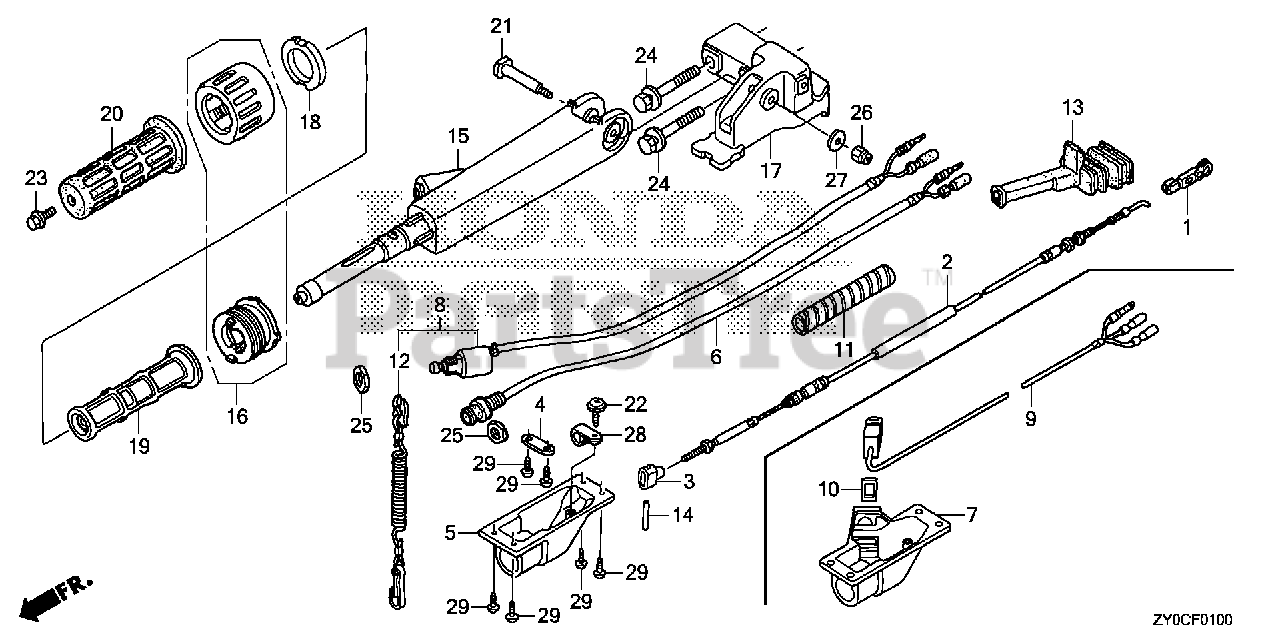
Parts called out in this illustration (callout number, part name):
1	LINKAGE, PIVOT
2	CABLE, THROTTLE
3	PIVOT, THROTTLE CABLE
4	PLATE, SHIFT
6	SWITCH ASSY., STARTER
7	COVER, SWITCH (PT)
8	SWITCH ASSY., EMERGENCY STOP
9	SWITCH ASSY., POWER TILT
10	STAY, POWER TILT SWITCH
11	TUBE, SPIRAL B
12	WIRE, EMERGENCY
13	GROMMET, OIL CASE (A)
14	PIN, THROTTLE CABLE
15	HANDLEBAR *NH246* (LOOSY GRAY)
16	GRIP, THROTTLE FRICTION (FOR U.S.A.)(COO)
17	BRACKET, HANDLEBAR *NH246* (LOOSY GRAY)
18	PAD, THROTTLE FRICTION
19	PIPE, GRIP
20	RUBBER, GRIP
21	SCREW, HANDLE PIVOT
22	SCREW, TAPPING (4X10)
23	BOLT, FLANGE (6X12)
24	BOLT-WASHER (10X55)
25	NUT, HEX. (16MM)
26	NUT, SELF-LOCK (8MM)
27	WASHER (8MM)
28	CLIP, WIRE HARNESS (6.3MM)
29	SCREW, TAPPING (4X12)
